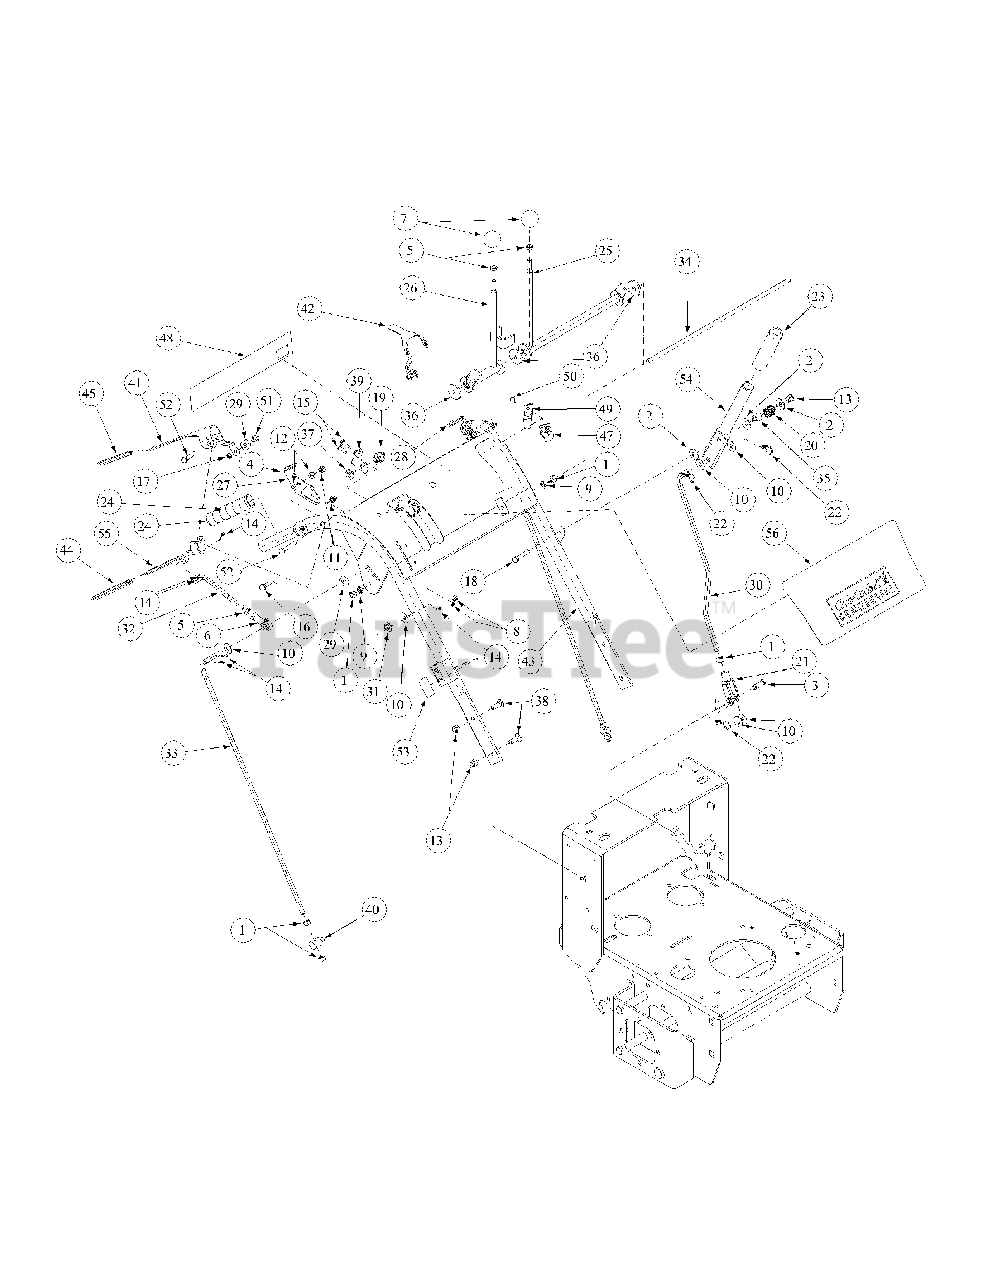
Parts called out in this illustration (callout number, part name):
1	Hex Nut, 3/8 - 16
2	Flat Washer, SS, 3/8
3	Clevis Pin, 3/8 x 1 1/8
4	Grip, 1.25, Black Neutral Lock
5	Hex Nut, Jam, 3/8-24
6	End Rod, 3/8
7	Knob, 1-3/8 x 1-19/64, 3/8-24
8	Lock Nut, Nylon Insert, 1/4-20
9	Lock Washer, 3/8 Zinc
10	Flat Washer, 3/8, SAE
11	Nut, 5/16-18
12	Flat Washer, SAE 5/16
13	Lock Nut, Nylon Insert, 3/8-16
14	Cotter Pin, 5/32 x 1-1/2 Zinc
15	HHCS, 1/4-20, .75
16	HHCS, Standard, 5/16-18 x 2
17	Lock Nut, Nylon Insert, 1/4 - 28
18	Carriage Bolt, 3/8 -16 x 2
19	Switch Operator's Presence
20	Spring, .850
21	Yoke, 3/8 - 16, Female
22	Hair Pin, 3/8 - 1/2
23	1" Grip, Black Handle
24	4-5/8" Grip, Black Plastic Handle
25	Control Assembly, Speed Hydro, LH
26	Control Assembly, Speed Hydro, RH
27	Latch, RH, Neutral Hydro
28	Latch, LH, Neutral Hydro
29	Hydro, Spacer Control Rod
30	Blade Clutch, Hydro Rod Base
31	Hydro Bush Control Rod
32	Control Rod, Short Hydr
33	Control Rod, Long Hydr
34	Hydro Rod, Speed Control
35	Sleeve Spring, 32/36/4
36	Friction Washe
37	Hex Nut, Dead Man Switch
38	Carriage Bolt, 3/8 -16 x
39	Mounting Switch, Neutral, Safet
40	Pivot, Belt Tightene
41	Operator Presence Control Handle, R
42	Operator Presence Control Handle, L
43	Hydro, Handle Assembl
44	Control Sleeve, Drive Black
45	Operators Control Sleeve,Yellow
46	Harness Adapter Assembly
47	Snap Mounting Switc
48	Handle Label
49	Retension Spring
50	Screw, TT, 10-24,
51	Shoulder Screw, .38 x .412, 1/4-2
52	HHCS, 5/16-18, 2.00
53	Parking Brake Deca
54	Blade Clutch Lever
55	Lever Assembly Control
56	Label, Pane
